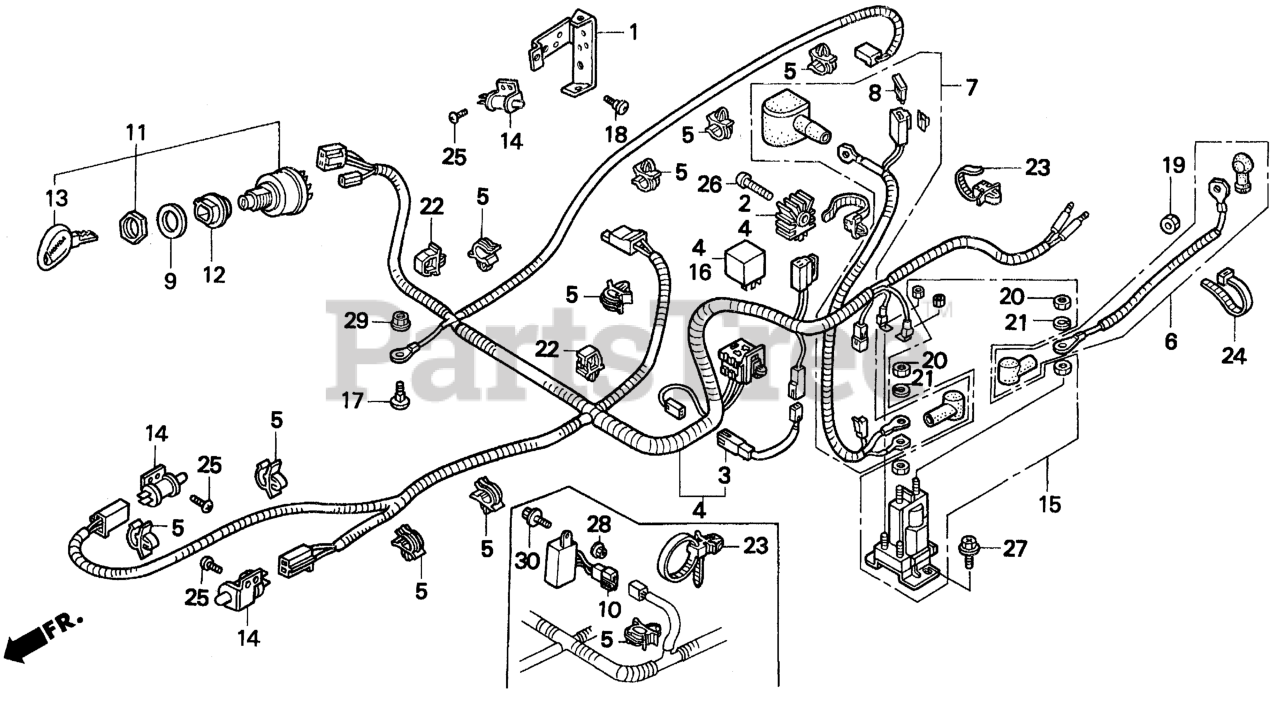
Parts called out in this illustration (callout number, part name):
4	WIRE HARNESS ASSY., MAIN
5	CLIP, WIRE HARNESS
9	COLLAR, FR. TURN SIGNAL
10	CONTROL ASSY., ENGINE
11	SWITCH ASSY., COMBINATION
12	BASE, COMBINATION SWITCH
13	KEY, COMBINATION SWITCH
14	SWITCH ASSY., P.T.O. CLUTCH
17	BOLT, SPECIAL (9X15)
22	CLIP, HARNESS (15MM) (BLUE)
23	STRAP, CABLE (105MM) *NH1* (Honda Code 1685536). (BLACK)
25	SCREW, TAPPING (5X8) (NOT AVAILABLE)
28	NUT, FLANGE (6MM)
29	NUT, FLANGE (8MM)
30	BOLT, FLANGE (6X12) Use from Engine SN 2086984.
